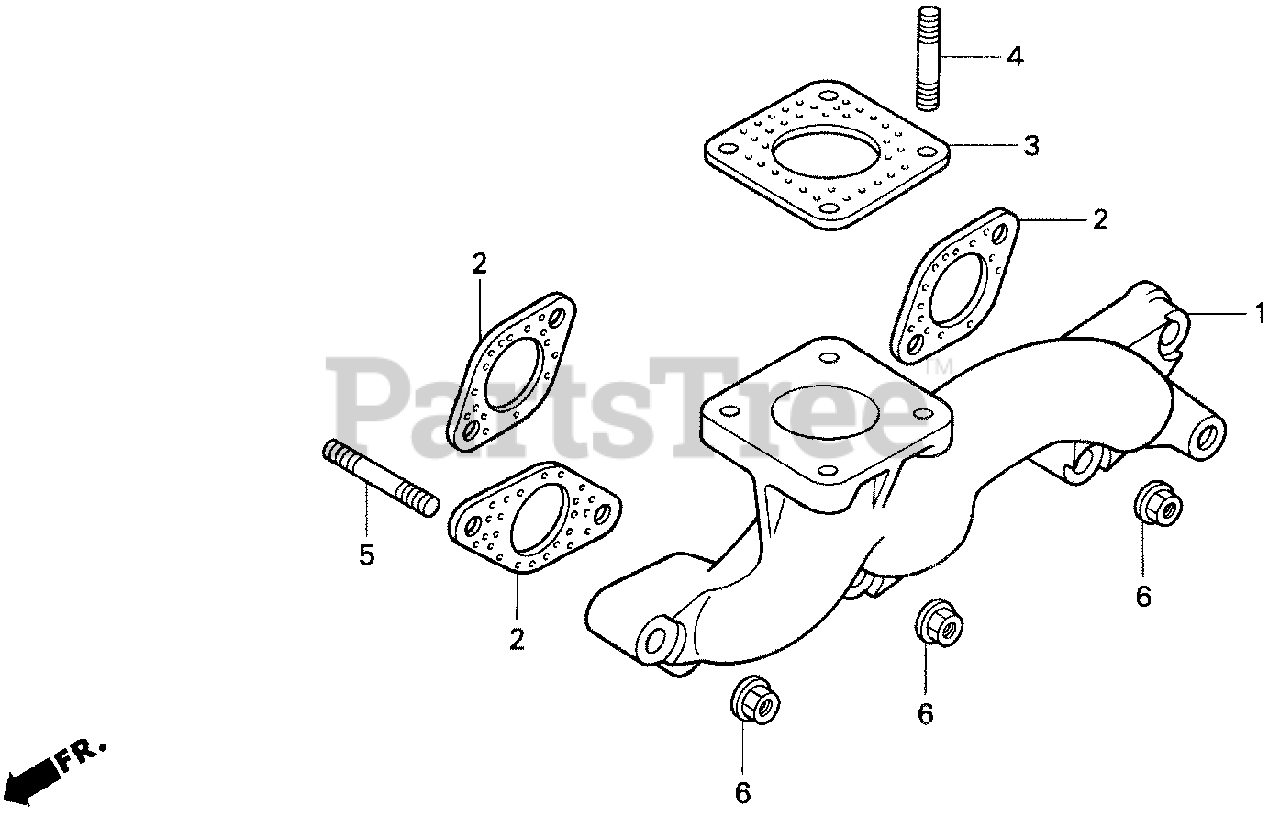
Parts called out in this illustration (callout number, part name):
1	MANIFOLD, EX.
2	GASKET, EX. MANIFOLD
3	GASKET, MUFFLER
4	BOLT, STUD (8X22)
5	BOLT 2, STUD (8X35)
6	NUT, FLANGE (8MM)
